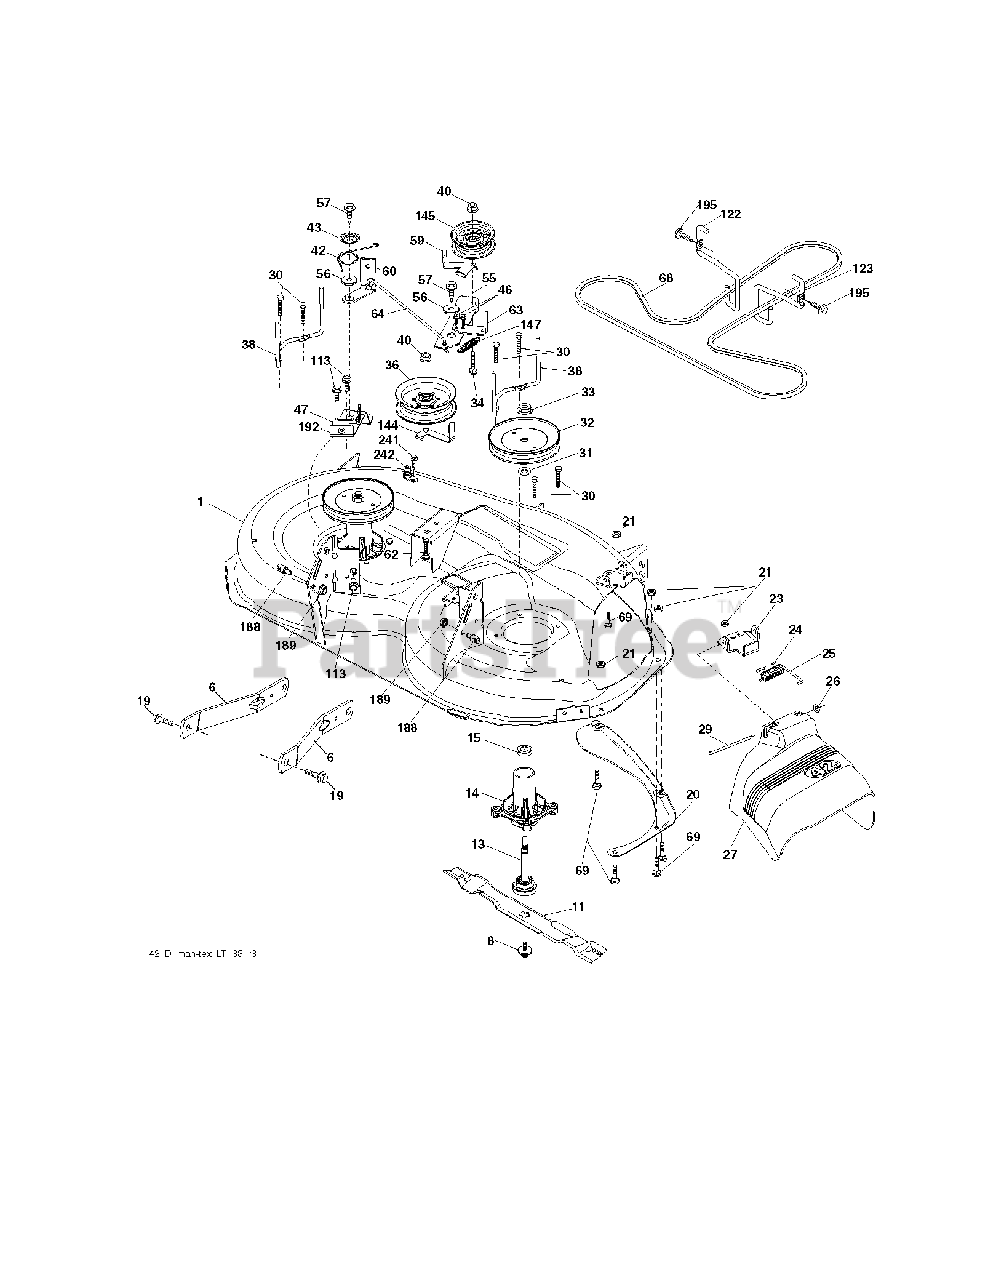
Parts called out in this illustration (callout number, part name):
2	BOLT
6	ARM.SUSPENSION.MOWER.R
7	SCREW.#10 X 0.750.BOS (2 2)
8	BOLT.WASHER.ASM.7/16-2
11	42" HI-LIFT BLADE
13	SHAFT.ASM.MDRL.N/GREASE.38
14	HOUSING.MANDREL.4PT.
19	BOLT.SHOULDER
20	BAFFLE.VORTEX
21	LOCKNUT
23	BRKT.DEFLECTOR.38"2005+
24	CAP-SLEEVE LT
25	SPRING.TORSION.DEFLECT
26	NUT PUSH M
27	SHIELD.DEFLECTOR.MOWER.42"BLAC
29	ROD.HINGE
30	SCREW, WASHER HEAD
31	WASHER.SPACER.MANDREL
32	PULLEY.MANDREL.5.438.PD
33	NUT.FLANGE.LOCK.TOP
34	BOLT.3/8-16X1.50
36	PULLEY.IDLER.2006
38	KEEPER.BELT.MANDREL.PULLEY
40	NUT LOCK FLG 3/8-16 UNC
42	SPRING.TORSION.BRAKE
43	SRPING.TORSION.RETAINE
46	SCREW.1/4-20X5/8
47	BRKT.CLUTCH.CABLE
55	IDLER.ARM.42"
56	SPACER.RETAINER
57	SCREW 3/8-16X1
59	GUARD, BELT
60	ARM BRAKE MOWER
62	BOLT
64	LINK BRAKE
67	HANDLE.CLUTCH.CABLE.LT
68	BELT.DECK.DRIVE.42"
69	BOLT
70	CLUTCH.ASM.MANUAL
111	BRKT.WHEEL.GAUGE.LH.42"
112	BRKT.WHEEL.GAUGE.RH.42"
113	BOLT.5/16HEX.WHS.HD
116	BOLT M
117	WHEEL.GAGE.HALF.SPOKED
118	LOCKNUT
119	WASHER
122	KEEPER BELT ENGINE LH
123	KEEPER BELT RH
144	KEEPER.BELT.MOWER
145	PULLEY.IDLER.48"PRIMARY
147	RETURN SPRING
152	CABLE.CLUTCH.MANUAL.
188	STUD.FASTNER.W/ANTI-ROTATE
189	NUT LOCK HEX FLANGE 5/16-18
192	BRKT.BRAKE.STAND.LH.
195	SCREW, 3/8-16X3/4
241	SCREW.TT.#10-32X.5.3/8.FLANGE
242	PORT.WASHOUT
